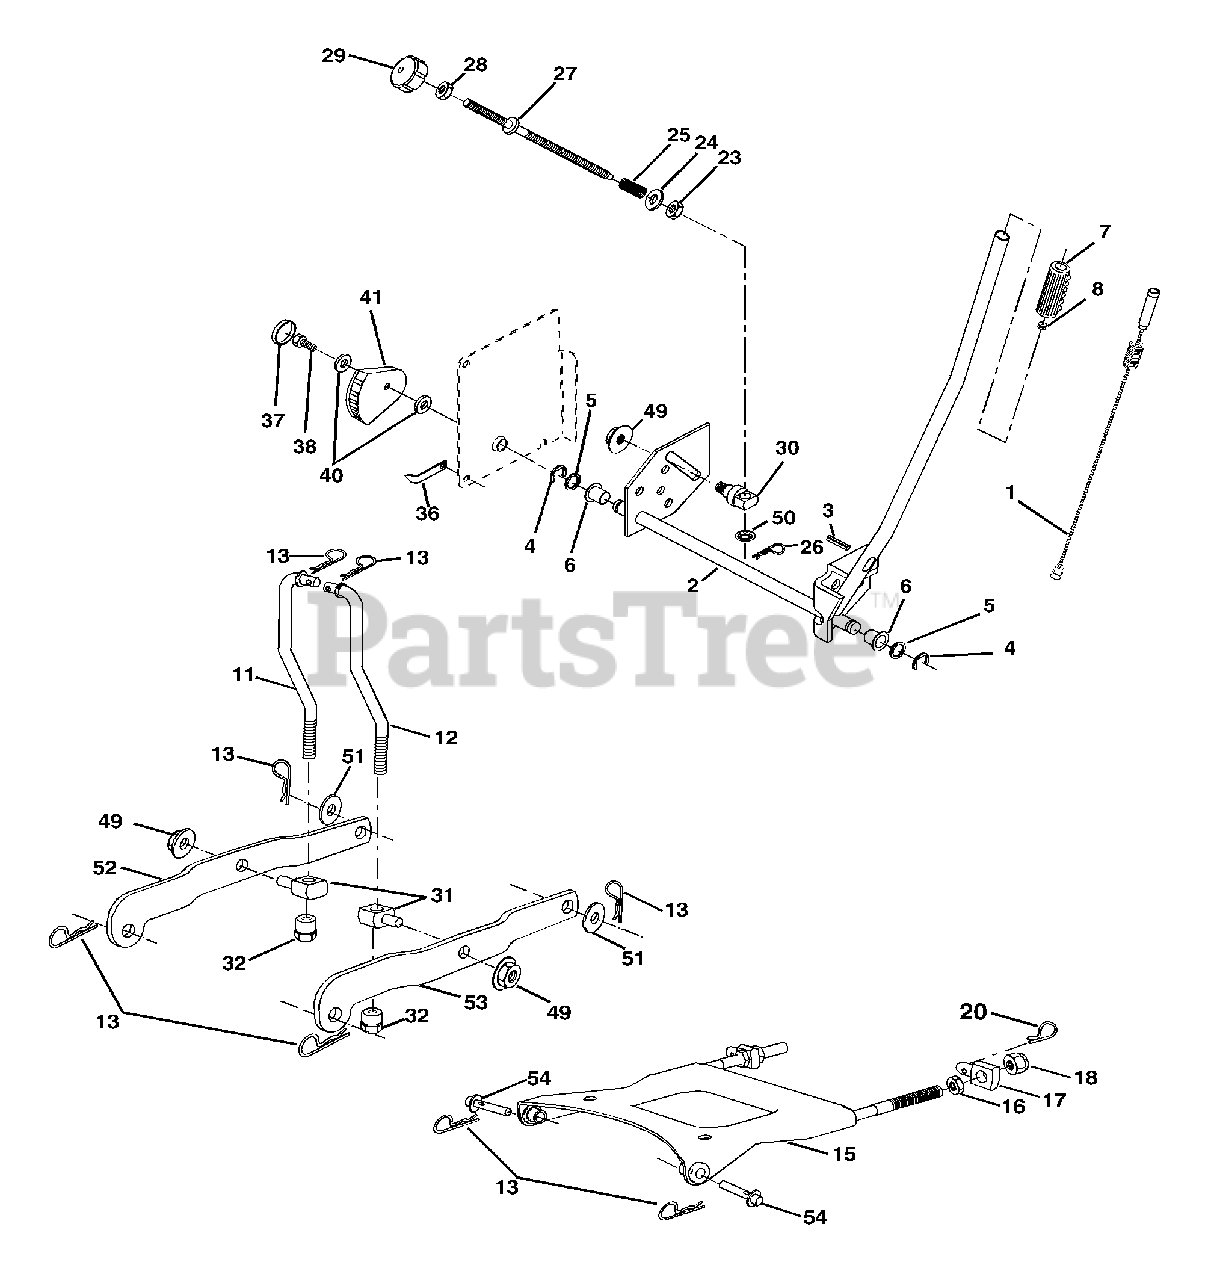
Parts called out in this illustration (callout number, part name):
1	Wire Asm Inner/Sprg W/plunger
2	Shaft Asm Lift RH w/Inf
3	Pin Groove
4	E Ring #5133-62
5	Washer 21/32 x 1 x 21 Ga
6	Bearing Nylon Blk 629 Id
7	Grip Handle
8	Button Plunger
11	Link Lift LH
12	Link Lift RH
13	Retainer Spring
15	Plate Asm. Suspension Front
16	Nut Jam Hex 1/2-13 Unc
17	Trunnion Front Susp.
18	Nut Lock w/Wsh 1/2-13unc
20	Retainer Spring
23	Nut Special
24	Washer 13/32 x 5/8 x 16 Ga
25	Spring
26	Retainer Clip
27	Rod Adj Lift
28	Nut Hex Jam 3/8-16 Unc
29	Knob Inf 3/8-16 Unc Blk W/sym
30	Trunnion Infin Height
31	Trunnion Susp. Arm
32	Nut Lift Link 7/16-20
36	Pointer Height Indicator
37	Plug Hole Blk 1.485/1.515 Dia.
38	Screw 5/16-18 x 1
40	Washer 11/32 x 1-1/2 10 Ga.
41	Indicator Height STLT
49	Nut Hex Flange Lock
50	Nut PUsh Phos & Oil
51	Washer 17/32 x 7/8 x 16 Ga.
52	Arm Susp. Rear LH
53	Arm Susp. Rear RH
54	Pin
